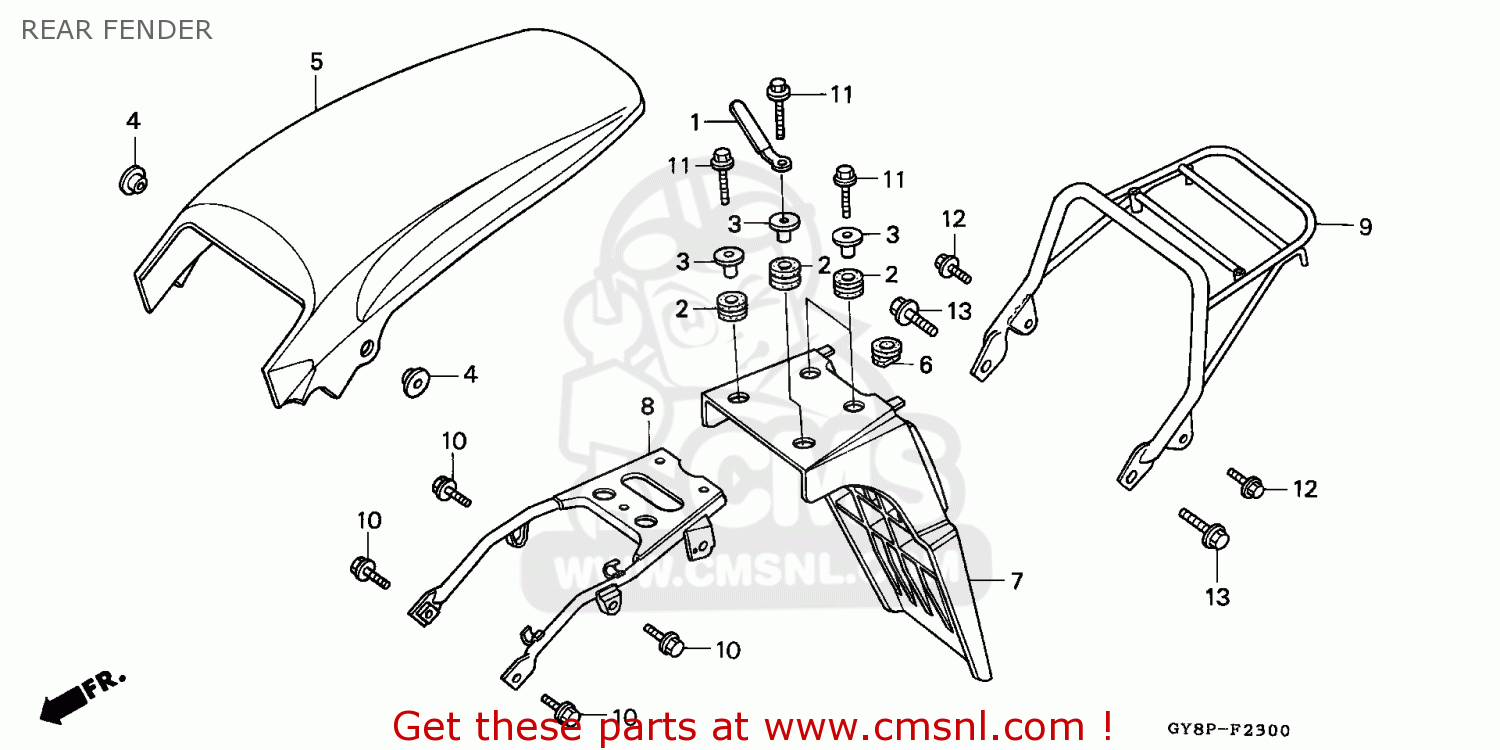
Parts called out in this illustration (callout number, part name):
1	CLIP,SUB CORD
2	RUBBER,FR-FEND.MT
3	COLLAR,FR.FENDER
4	METAL,FENDER FIX
5	FENDER REAR NH4
6	RUBBER, CUSHION
7	FENDER,B,REAR
8	STAY RR FENDER
9	CARRIER REAR NH1
10	BOLT,FLANGE,6X12
11	BOLT,FLANGE,6X25
12	BOLT,FLANGE,6X12
13	BOLT,FLANGE,DR 8X
